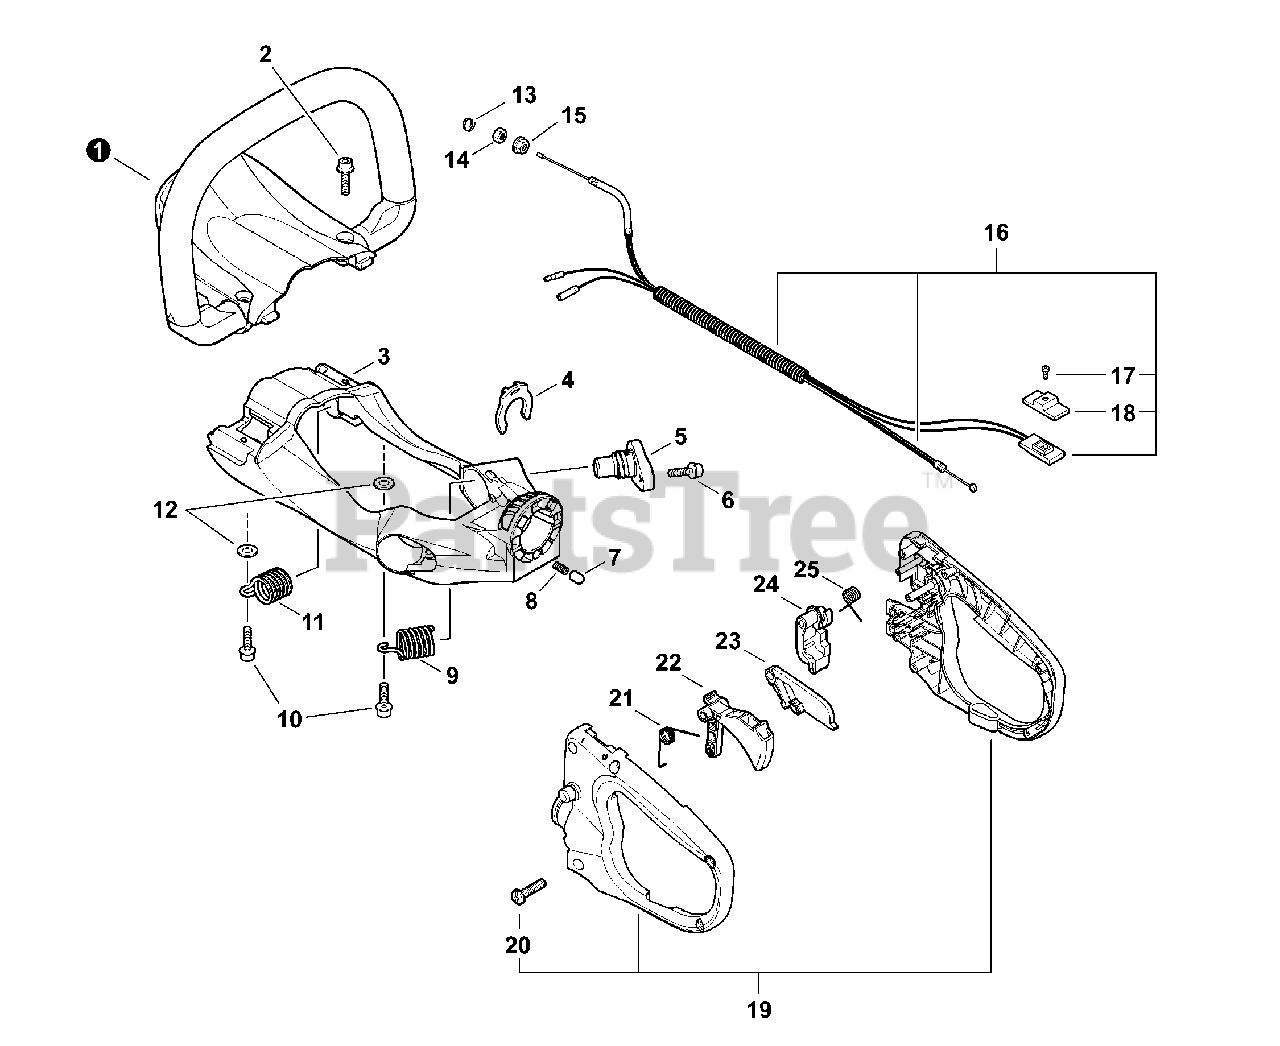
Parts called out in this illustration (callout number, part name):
1	HANDLE, FRONT
2	BOLT 5×20
5	HOLDER, SPRING
6	BOLT 5×20
7	PIN, CLEVIS
8	SPRING, COMPRESSION
9	SPRING, COMPRESSION
10	BOLT 5×16
11	SPRING, COMPRESSION
12	WASHER 5.5×12×0.8
15	NUT, FLANGE M6
16	CONTROL CABLE ASSY
17	SCREW 3×10
18	KNOB, SWITCH - ORANGE
19	REAR HANDLE SET
20	SCREW 4×16
21	SPRING, TORSION
22	TRIGGER, THROTTLE
23	LOCKOUT, THROTTLE
24	LEVER, HANDLE RELEASE
25	SPRING, TORSION
